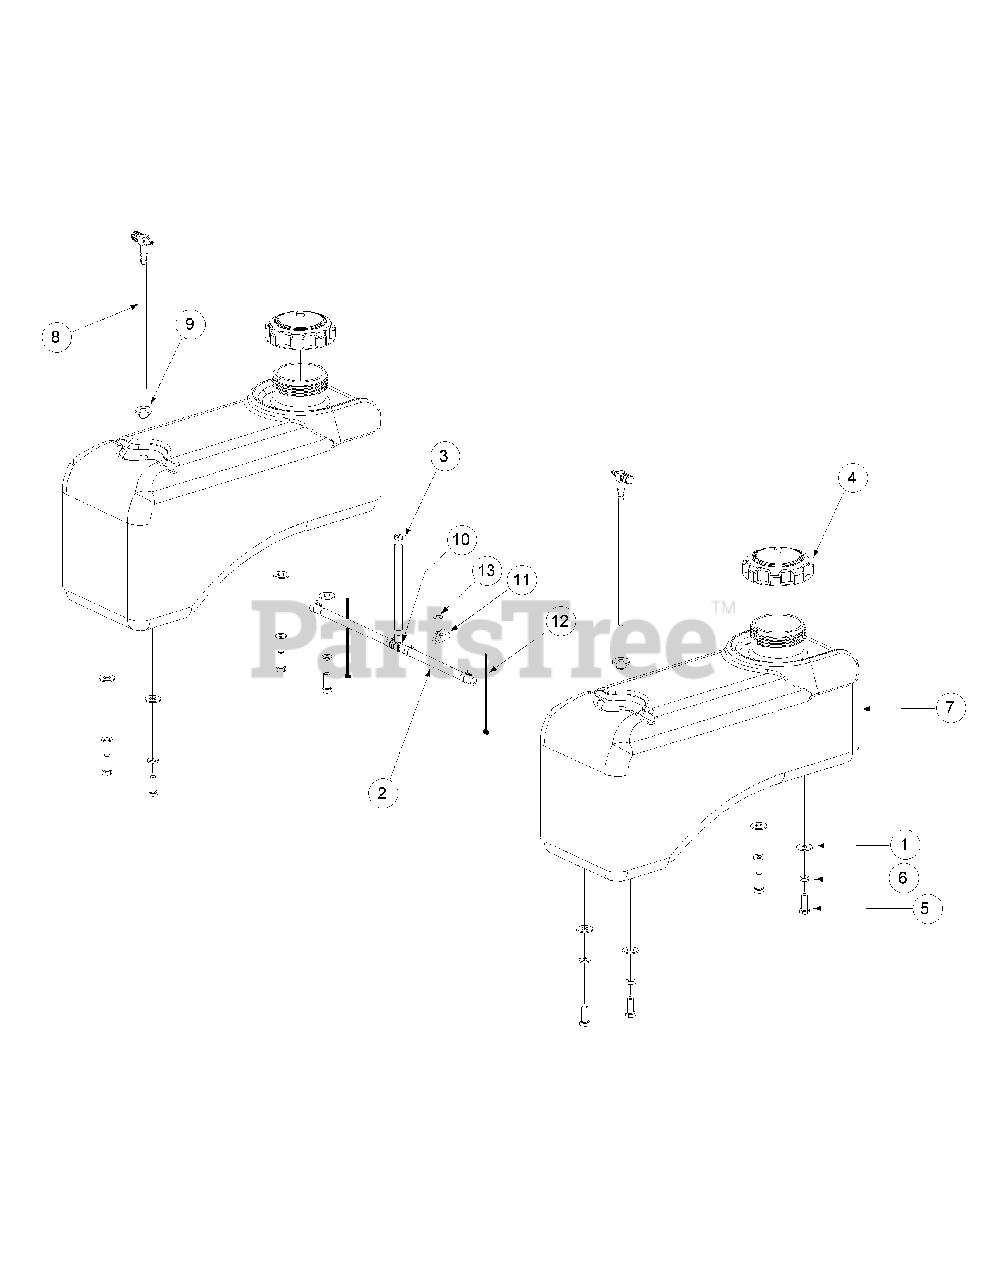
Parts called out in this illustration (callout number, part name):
1	Flat Washer, .406 ID, 1.0 OD, .105
2	Hose, 1/4" Fuel Line, 79.5"
3	Clamp, Union
4	Fuel Cap, 3.5
5	Hex, Cap Screw, 3/8-16, .88
6	Lock Washer, 3/8
7	Fuel Tank
8	Fuel Fitting
9	Grommet, Fuel Tank
10	Tee Fitting, Fuel
11	Clamp, 1/2 Tubing
12	Cable Tie
13	Flat Washer, 1.4 x .630 x .0515
